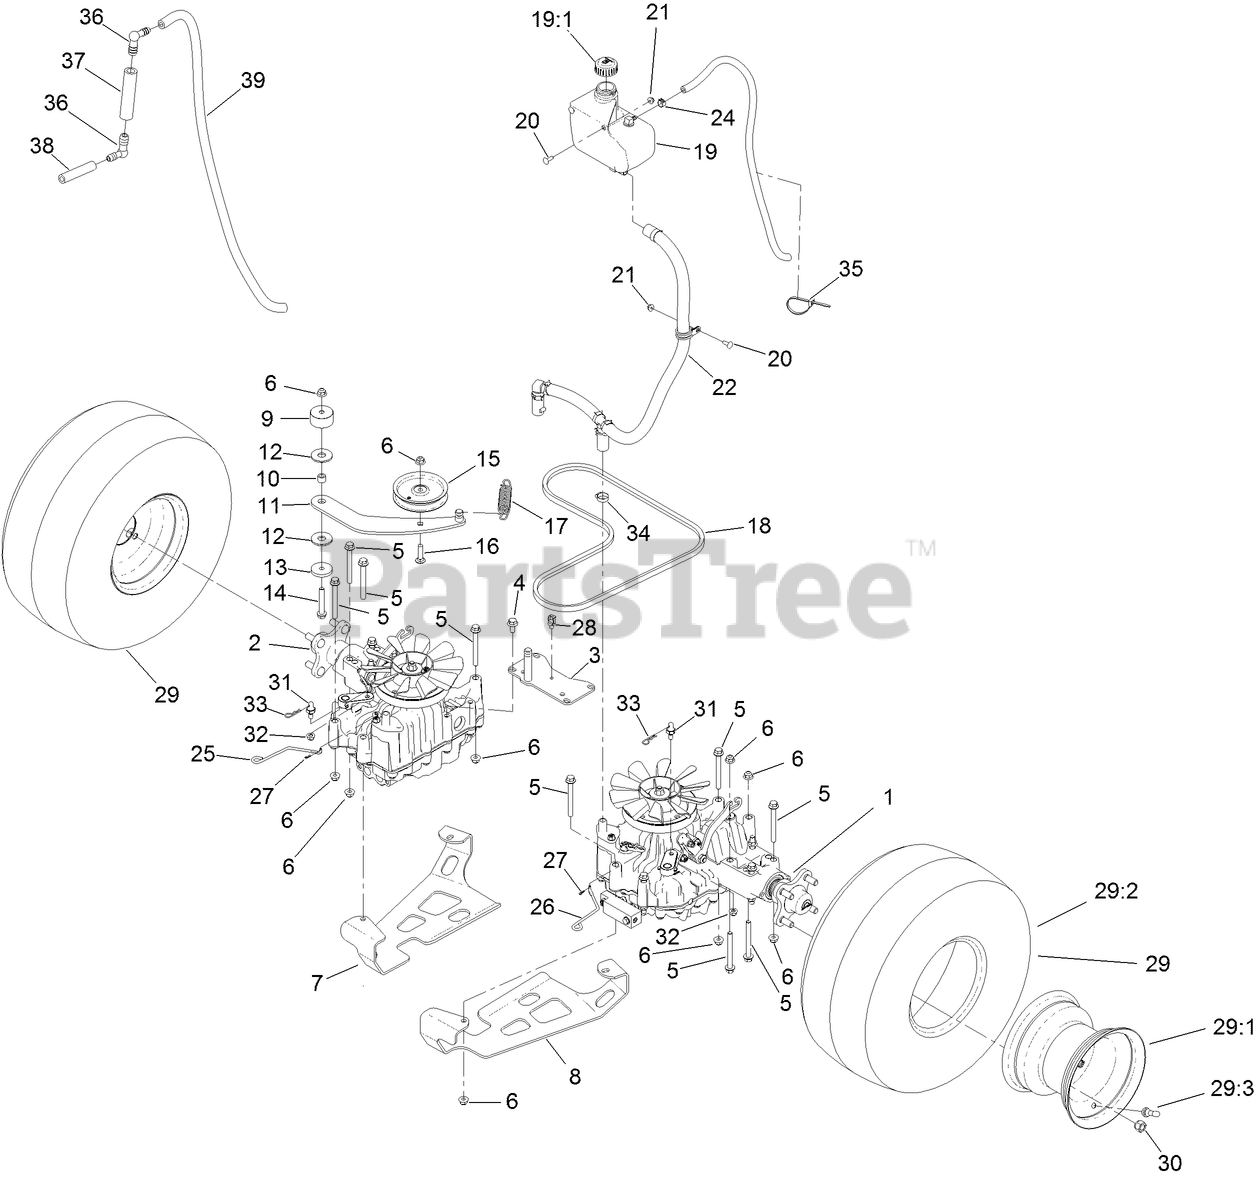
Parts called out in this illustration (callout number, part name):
1	LH TRANSMISSION ASM
2	RH TRANSMISSION ASM
3	SUPPORT-TRANSAXLE
4	SCREW-HHF
5	SCREW-HHF
6	NUT-HF, NI
7	PLATE-SKID, TRANSMISSION (RH)
8	PLATE-SKID, TRANSMISSION (LH)
9	SPACER
10	BUSHING-LEVER, LIFT
11	ARM-IDLER
12	WASHER-FRICTION, COMPOSITE
13	WASHER-PLAIN
14	SCREW-HHF
15	PULLEY-IDLER
16	SCREW-HH
17	SPRING-EXTENSION
18	BELT-V
19	TANK-HYD
19:1	CAP-VENTED
21	NUT-HF
22	HYD HOSE ASM
24	CLAMP-HOSE
25	ROD-BYPASS, RH
26	ROD-BYPASS, LH
27	PIN-HAIR
28	CLIP-TIE
29	WHEEL AND TIRE ASM
29:1	RIM-8 INCH, GRAY
29:2	TIRE
30	NUT-LUG
31	SPACER-HEX
32	NUT-HF, NI
33	PIN-COTTER
34	CLAMP-DRIVE, WORM
35	TIE-CABLE
36	FITTING-ELBOW 90
37	HOSE-VALVE, TANK
38	HOSE-FUEL
39	HOSE-FUEL
